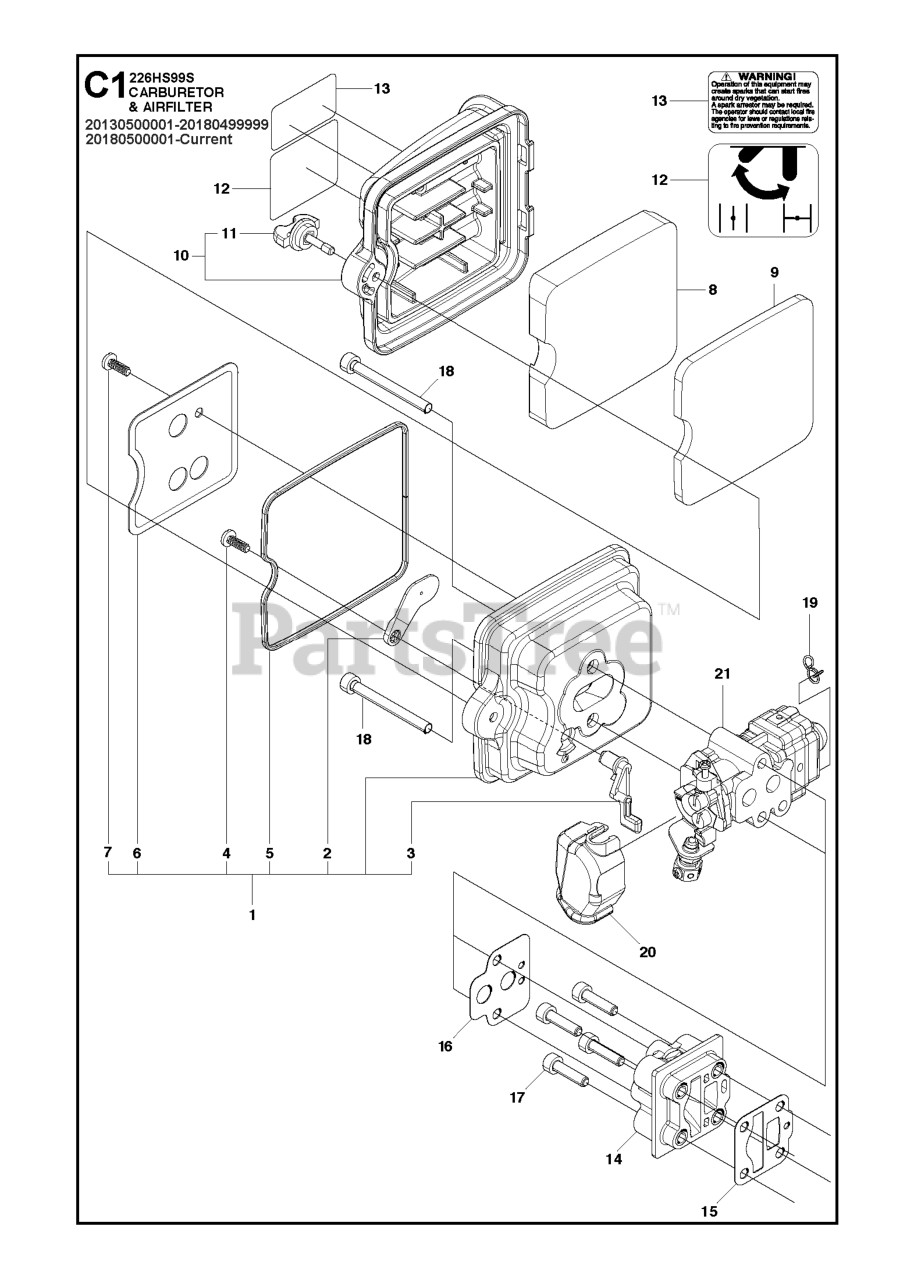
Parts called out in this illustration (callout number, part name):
2	PLATE.CHOKE
3	LEVER CHOKE
4	SCREW
7	SCREW
8	FILTER FOAM
10	COVER ASSY
13	LABEL
15	INSULATOR GASKET(R-848F0814B0)
15	GASKET
16	GASKET, CARB (RPLS T155113131)
21	CARBURETTOR ASSY
21	CARBURETOR ASSY
